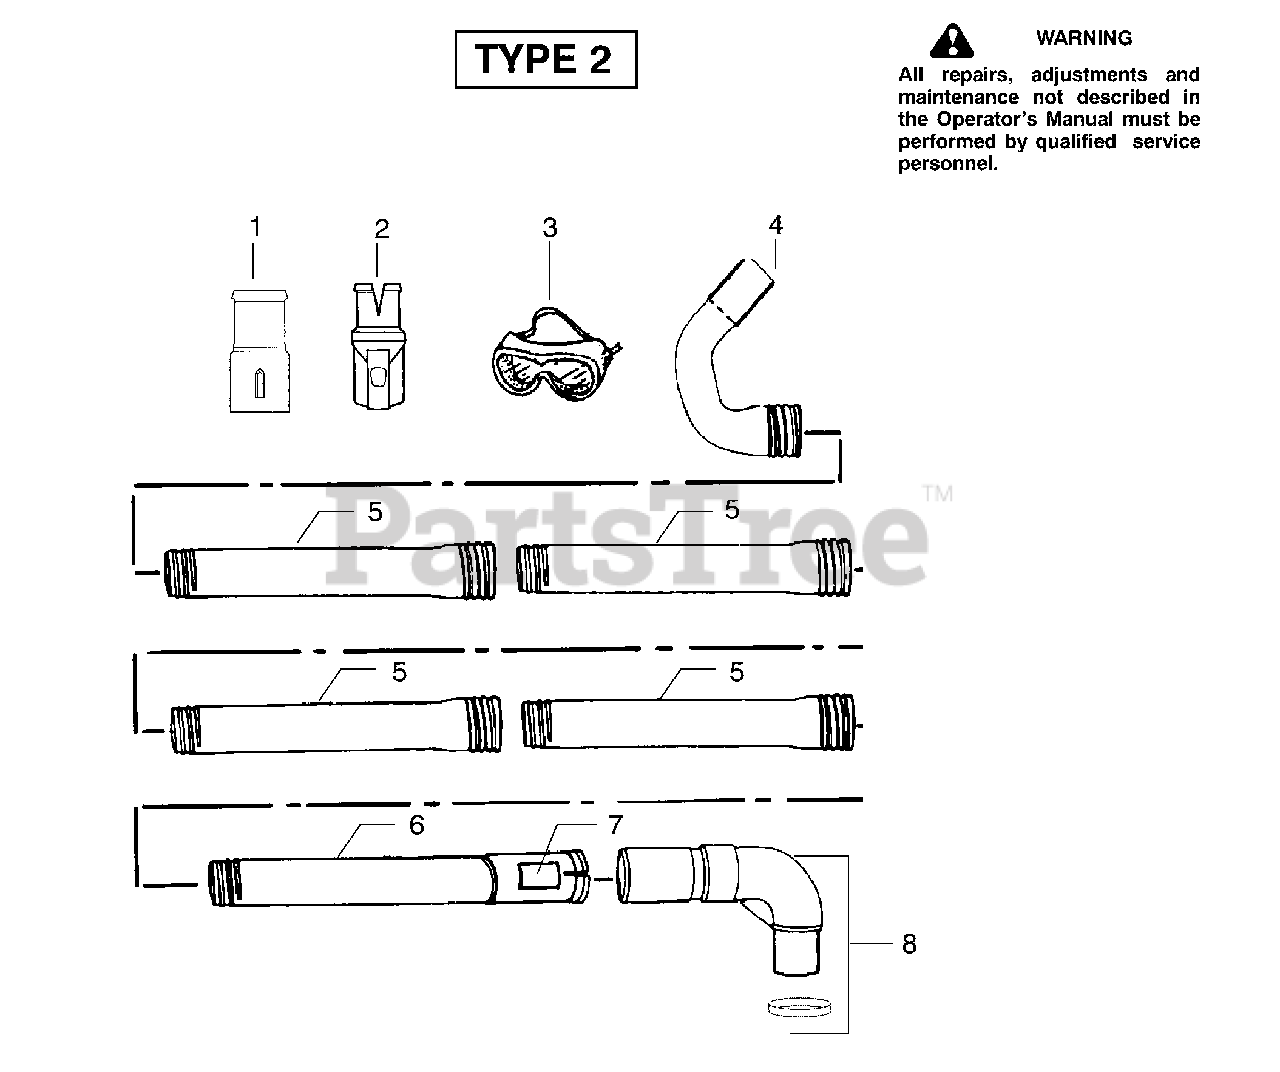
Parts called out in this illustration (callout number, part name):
1	Adapter-Tube
2	Adapter-Gutter Kit
3	Goggles
5	Tube-Extension
6	Pivot Tube
7	Decal-Warning
8	Elbow&Spacer Ring
